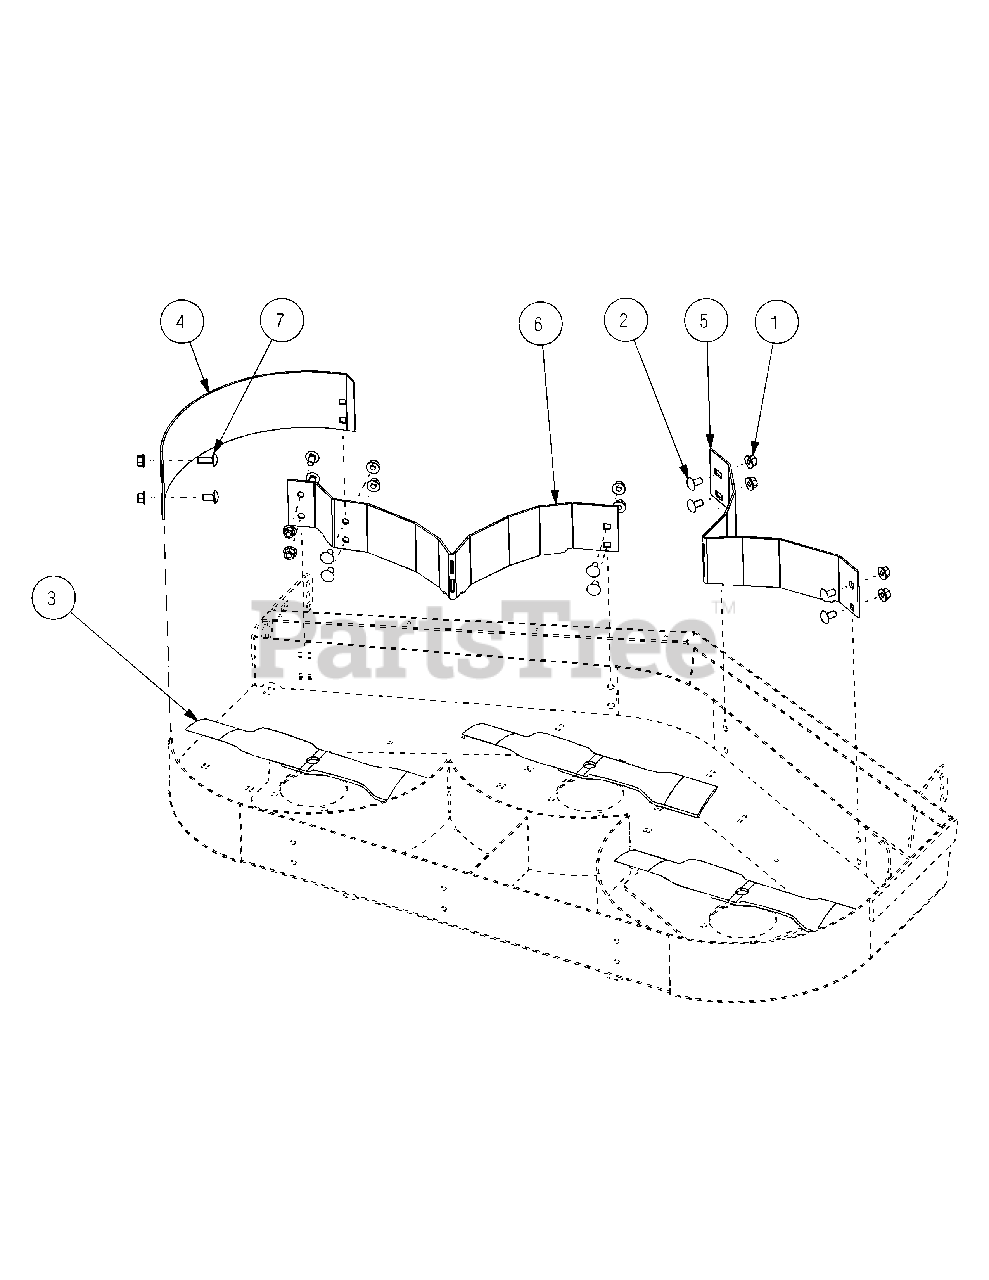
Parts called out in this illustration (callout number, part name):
1	Nut, Flange 3/8-16 Gr5
2	CARRIAGE BOLT 3/8-16 x .75
3	Blade, 17" Mulch
4	Baffle, Mulch RH
5	Baffle, Mulch LH
6	Baffle, Mulch Center
7	Bolt, Carriage 3/8-16 Gr 5
